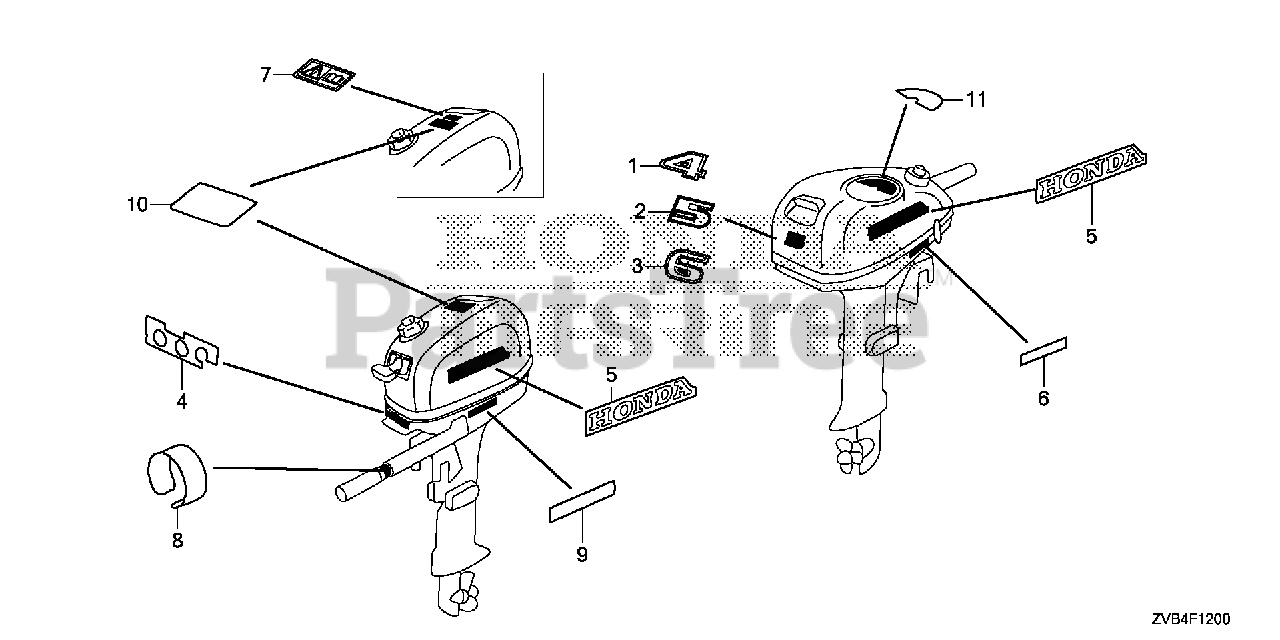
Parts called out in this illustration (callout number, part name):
2	MARK, RR. (5)
4	LABEL, INDICATION (E)
5	MARK, SIDE STRIPE (HONDA)
6	MARK, CHANGE FUEL PETCOCK (E)
8	MARK, THROTTLE (ENGLISH)
9	LABEL, STORING OILCAUTION (E)
10	LABEL, WARNING OPERATOR (ENGLISH)
11	MARK, EMERGENCY START (ENGLISH)
